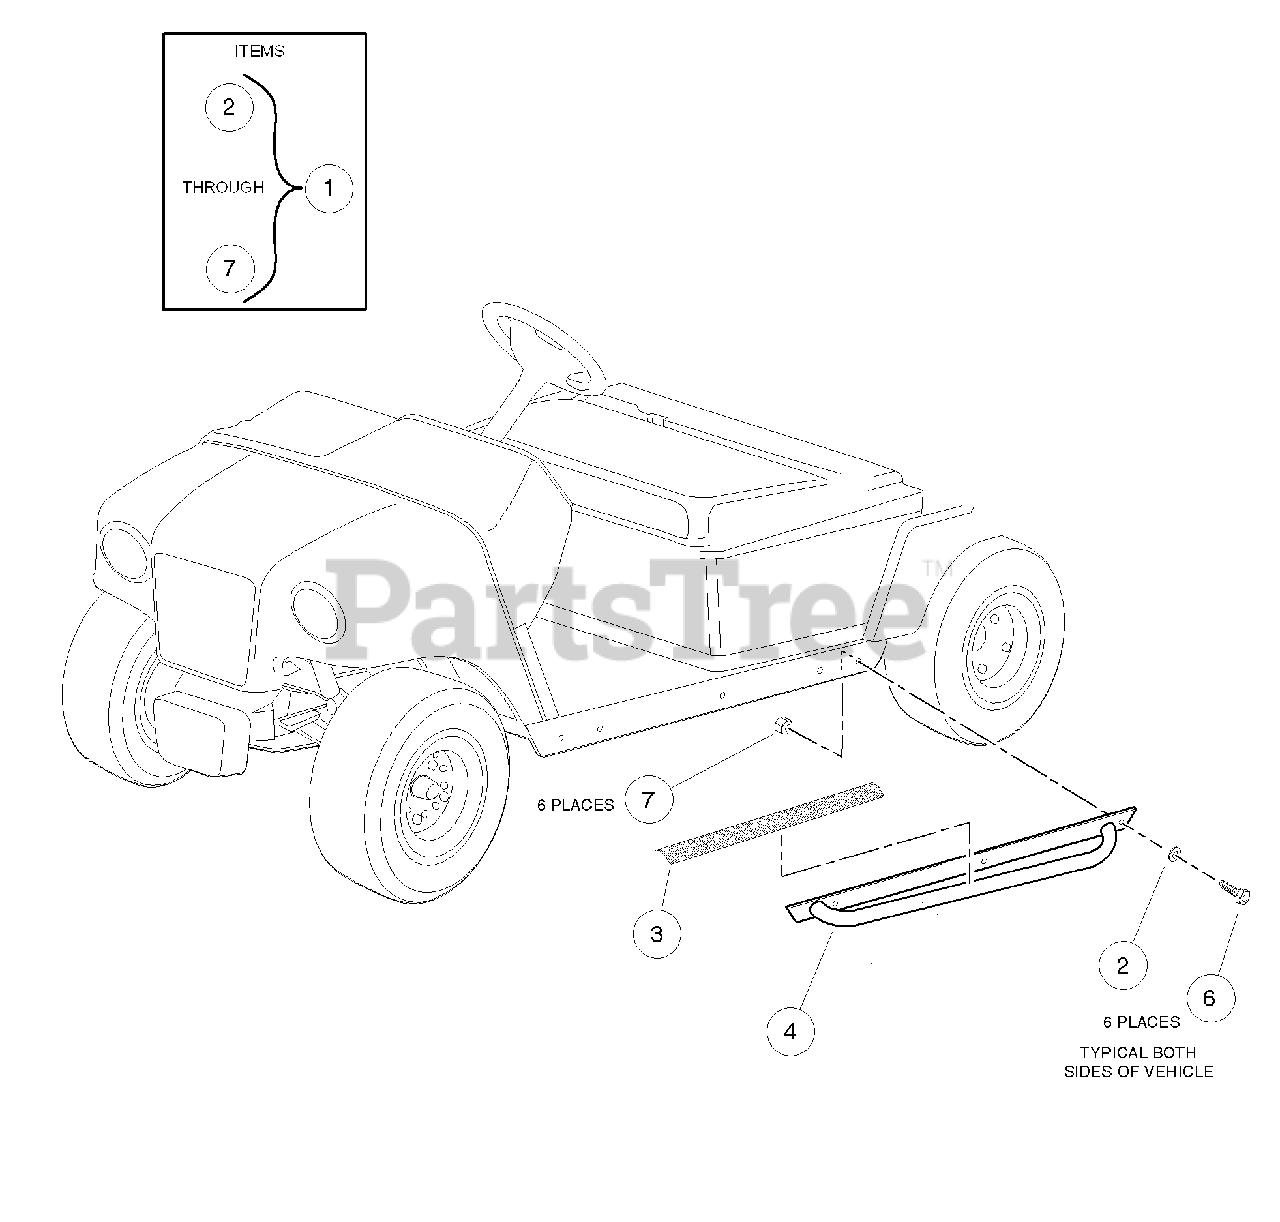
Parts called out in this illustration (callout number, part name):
1	Kit, Nerf Bar
2	Washer, 3/8 Flat
3	Tape, Non-skid
4	Asm, Nerf Bar, Driver
5	Asm, Nerf Bar, Passenger
6	Screw, 3/8-16 X 1.00 Hex-Head Cap
7	Locknut, 3/8-16 Hex
